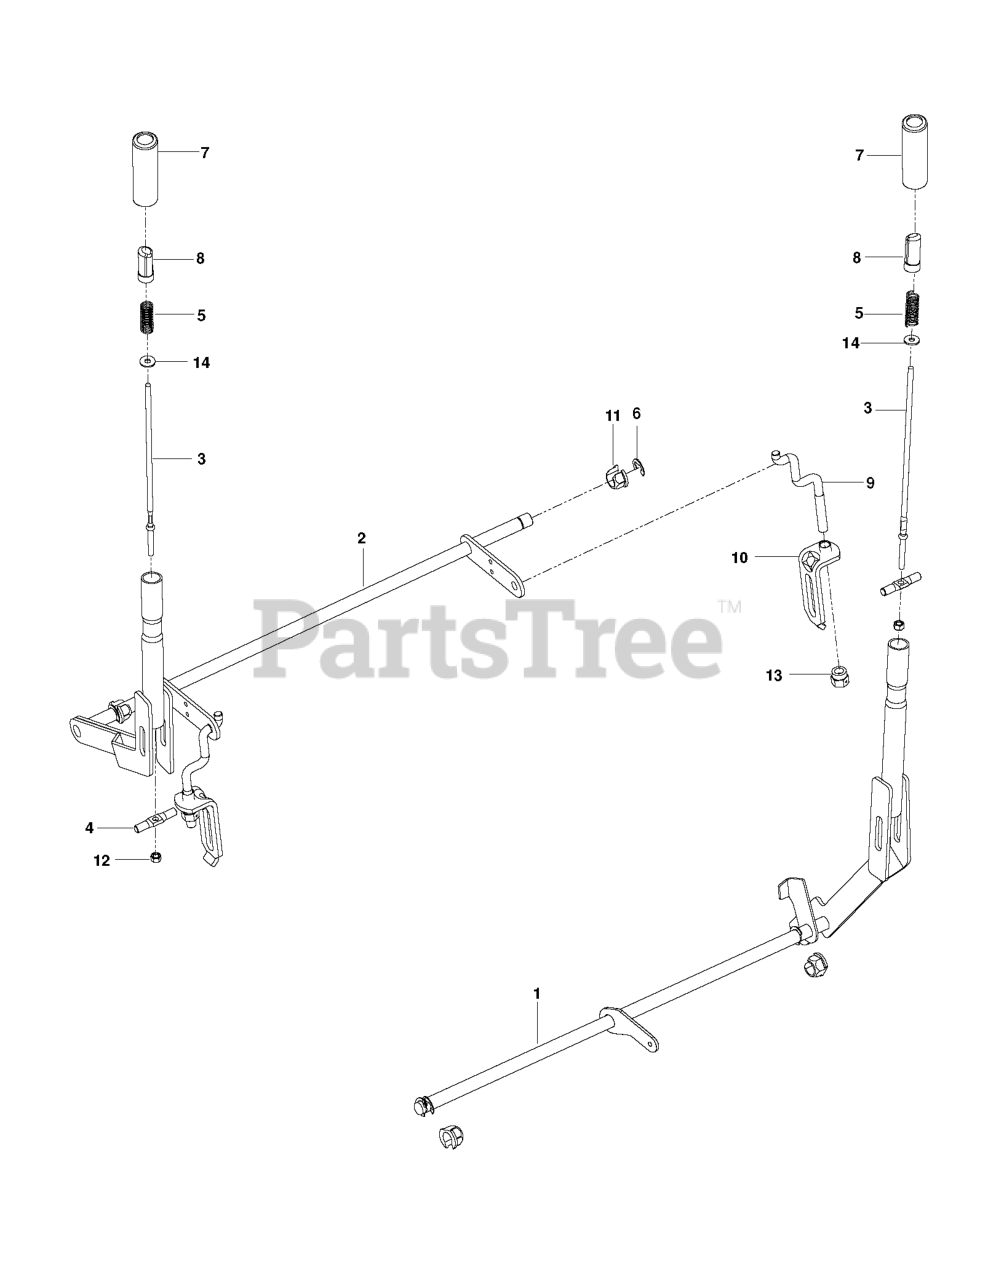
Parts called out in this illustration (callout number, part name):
1	Brake Shaft Subassembly Weldment, Med
2	Lifting Arm Weldment, Black
3	ROD, HANDLE RELEASE
4	Release Rod Latch
5	SPRING, COMPRESSION
6	RETAINING RING LT
7	GRIP, HANDLE, BLACK
8	BUTTON, PUSH, BLACK
9	LINK, REAR SUSPENSION
10	ASSEMBLY, BRKT LINK
11	PLASTIC NUT
12	LOCKNUT
13	NUT, LIFT LINK 7/16-20
14	WASHER PM
